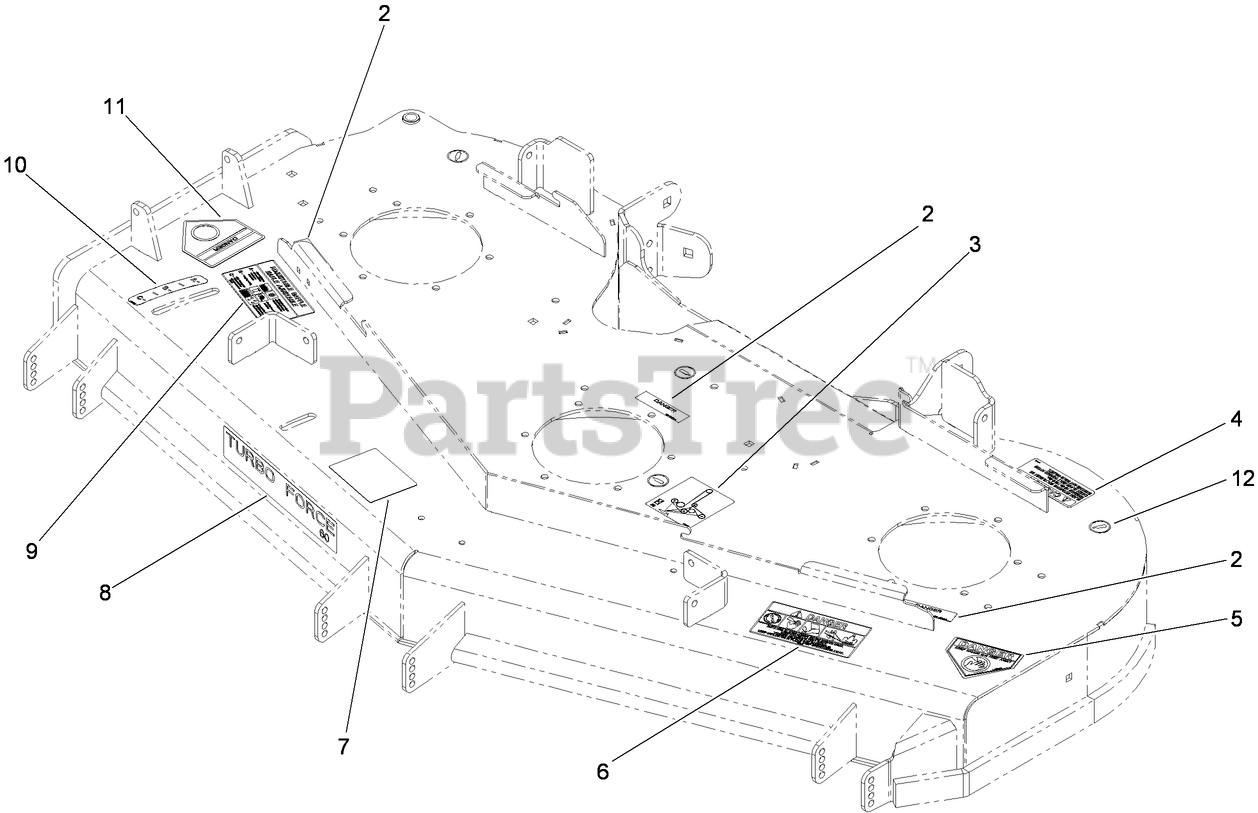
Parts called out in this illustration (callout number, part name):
2	DECAL-COVER, MISSING
3	DECAL-ROUTING, DECK BELT
4	DECAL-TORQUE
5	DECAL-DANGER
6	DECAL-DANGER, THROWN OBJECT
7	DECAL-SCALP, ANTI
9	DECAL-ADJUSTMENT, BAFFLE
10	DECAL-SETTING, BAFFLE
11	DECAL-DANGER
12	DECAL-GREASE
